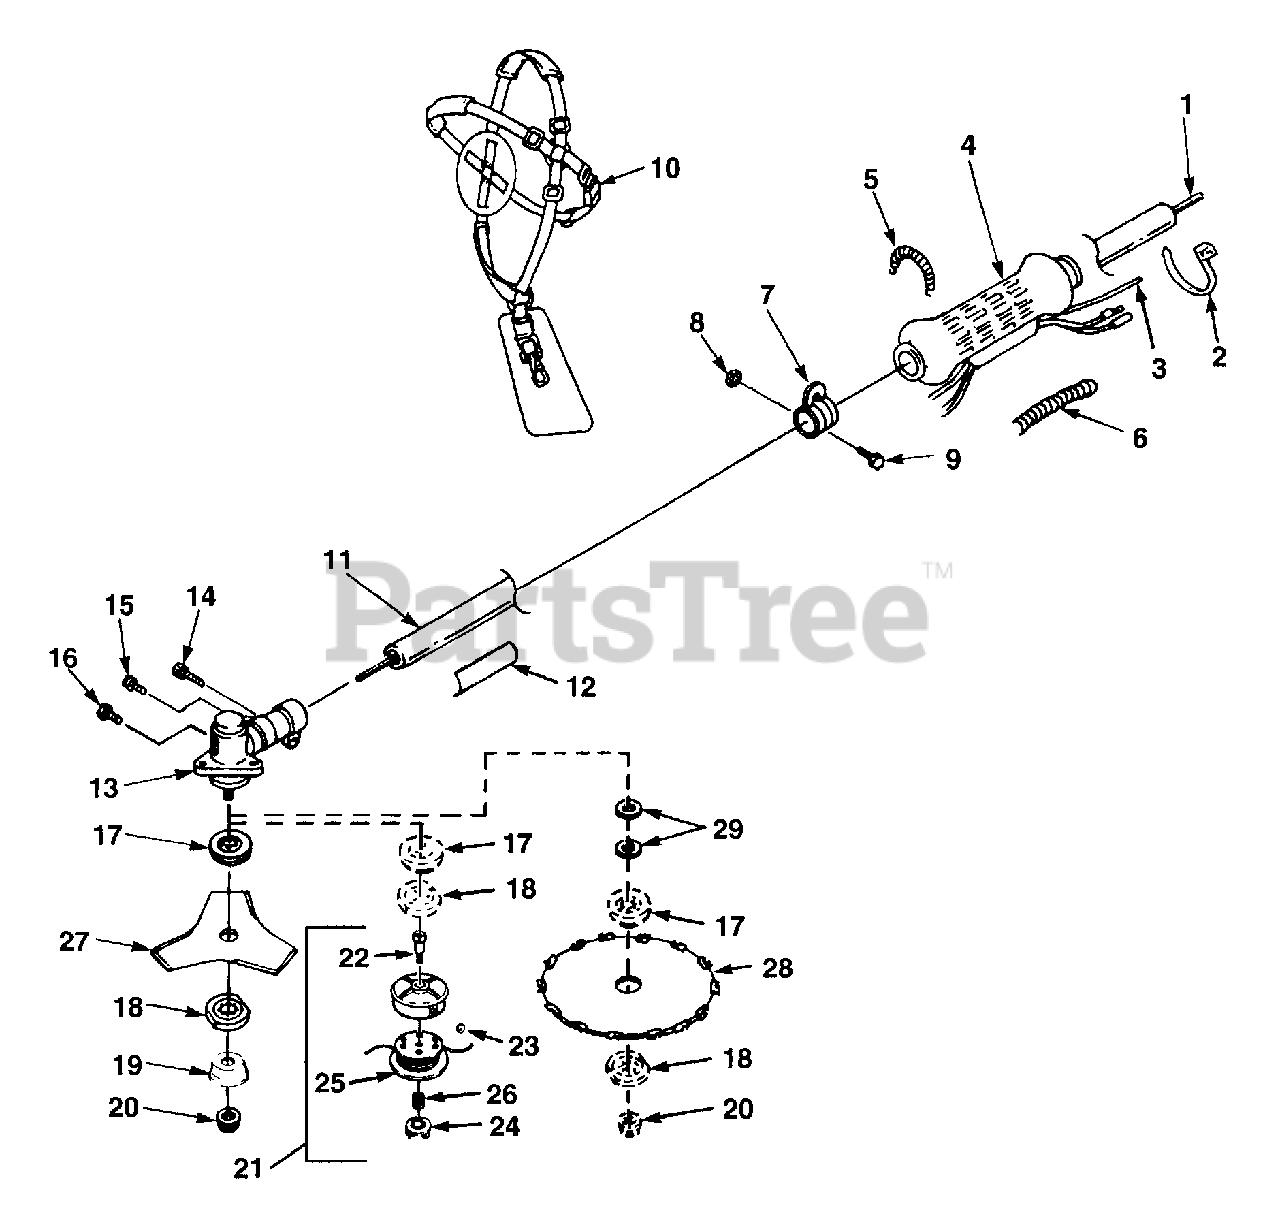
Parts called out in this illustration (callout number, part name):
1	DRIVE SHAFT
2	TIE-Cable
3	CABLE-Throttle
4	GRIP/HIP PAD
5	SPRING-Tension
6	SLEEVING
7	BAND-Hanger
8	NUT-Hex
9	BOLT & WASHER
10	HARNESS-Shoulder
11	HOUSING-Driveshaft
12	DECAL-Warning
13	GEAR HEAD
14	SCREW-Cap
15	SCREW & WASHER-Mach (M6)
16	SCREW-Grease
17	WASHER-Blade
18	WASHER-Blade
19	NUT-Guard
20	NUT-Gear Head
21	STRINGHEAD-Complete
22	CONNECTOR-Drive
24	KNOB (L.H.)
25	SPOOL w/Line
27	BLADE-Tri-Arc (10")
28	MACHETE BLADE KIT
29	SPACER
